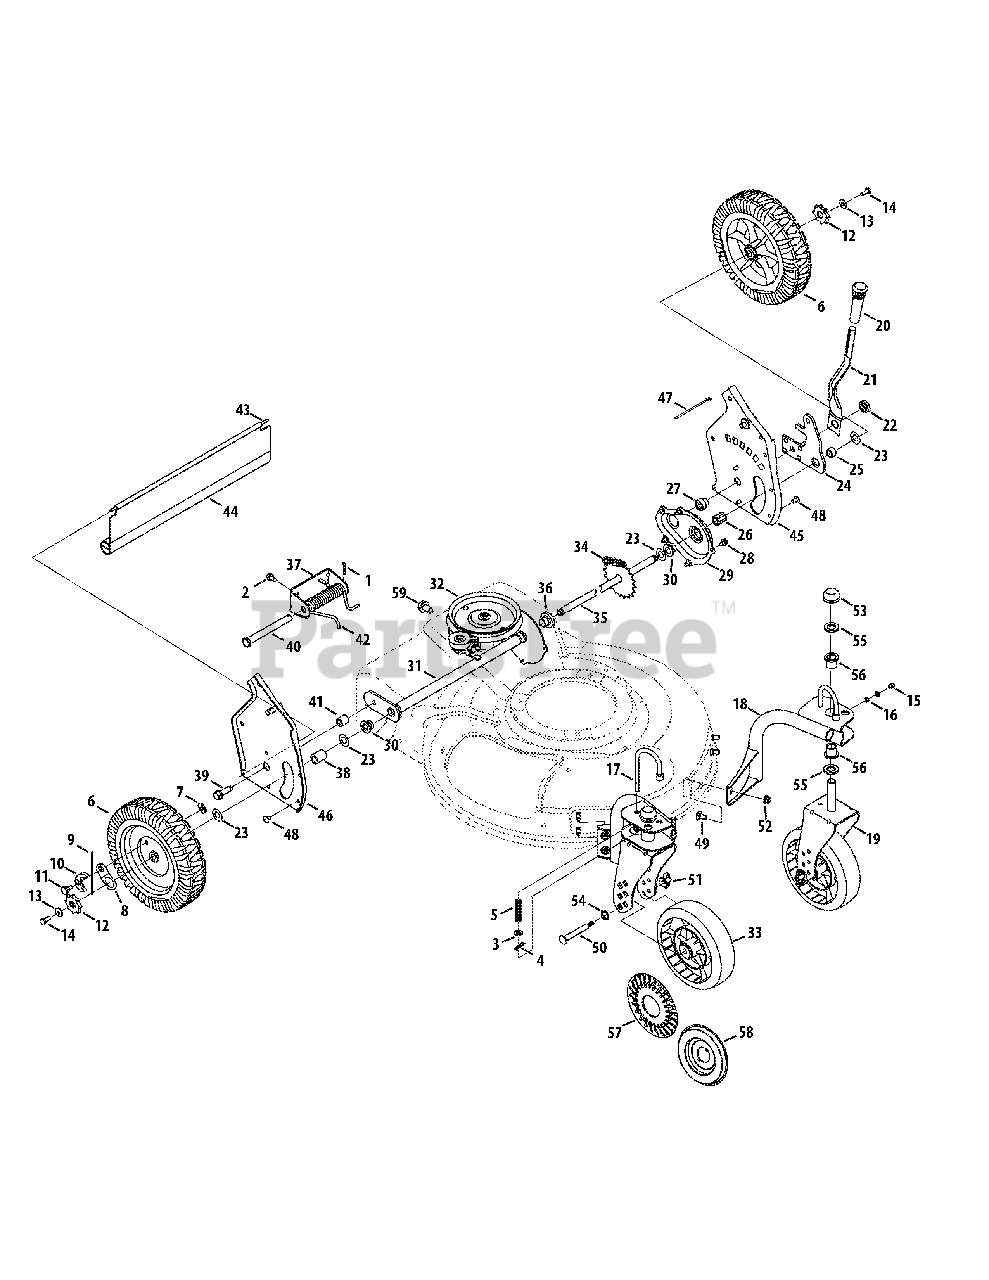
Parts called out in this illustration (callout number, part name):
1	Cotter Pin
2	Screw 1/4-14 x .825
3	Flat Washer.330 ID x.630 OD
4	Cotter Pin
5	Compression Spring
6	Wheel, 9 x 2.125
7	Top Lock Tab Weld Nut 1/4-20
8	Ratchet Pawl Plate
9	Plastic Spring Ratchet
10	Pawl RH
10	Pawl LH
11	Shlder Screw.340 ID x.285 OD
12	Wheel Ratchet
13	Bell Washer.265 ID x.75 OD
14	Hex Cap Screw 1/4-20 x.620
15	Grease Fitting
16	Flat Washer.203 ID x.403 OD
17	Wheel Pin Lock
21	Spring Lever
22	Shoulder Nut.825 x .165 Lg.
23	Flat Washer .508 ID x 1.0 OD
25	Spacer .510 ID x .70 OD
26	Slv Bearing .504 ID x .830 OD
27	Shlder Spacer, .385ID x .715Lg
28	Tap Screw 1/4-20 x .375
32	Transmission Ass’y Complete
33	Wheel 7 x 2
34	Chain
35	Rear Axle Assembly
36	Flge Bearing .506 ID x .715 Lg
39	Screw 3/8-16 x .25
40	Clevis Pin .50 Dia x 4.82 Lg.
41	Spacer .385 ID x .624 OD
42	Torsion Spring
43	Trail Shield Wire
44	Trail Shield
48	Screw 1/4-14 x.500
49	Carriage Bolt 5/16-18 x.62
50	Caster Axle
51	Wing Nut
52	Flange Lock Nut 5/16-18
53	Push Cap
54	Wave Washer.531 ID x.781 OD
55	Flat Washer.640 ID x 1.12 OD
56	Flange Bearing
57	Hubcap - Spoke w/ Hole
58	Hubcap - Radial Spoke
59	Screw, 5/16-18 x .625
